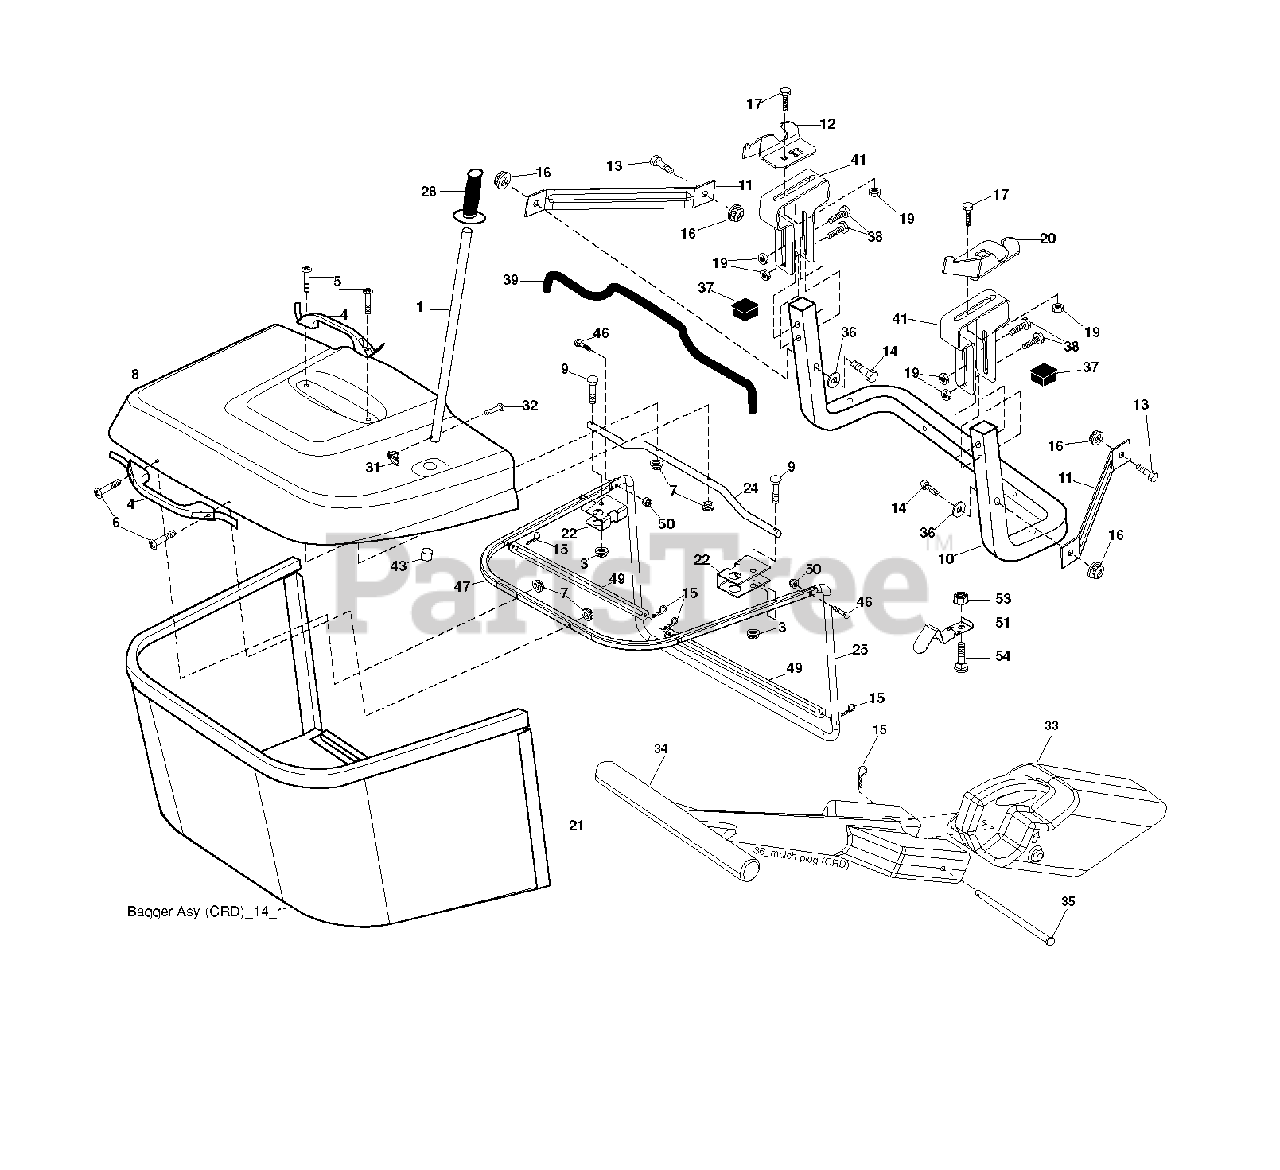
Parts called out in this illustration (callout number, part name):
1	TUBE HANDLE
3	NUT T
5	SCREW.PAN.HEAD
11	BRACKET
14	BOLT-HEX EAK
15	RETAINER-SPRNG RB
16	NUT LOCK FLG 3/8-16 UNC
17	BOLT
19	NUT LOCK HEX FLANGE 5/16-18
20	BRKT.PIVOT.RH.CRD
21	BAGGER.ASM.CRD.2007
22	BRACKET
24	TUBE
28	GRIP.HANDLE.BLACK
31	RETAINER CLIP
32	RIVET,DRILLED
33	PLUG
35	PIN
38	BOLT.5/16-18X2.5
39	SEAL.BAGGER.CRD
41	BRKT, BAGGER
43	PLUG, TUBING END
46	BOLT.CARRIAGE.5/16-18
50	NUT.71038.31-18.HEX.NYLOCK
53	NUT
54	BOLT
